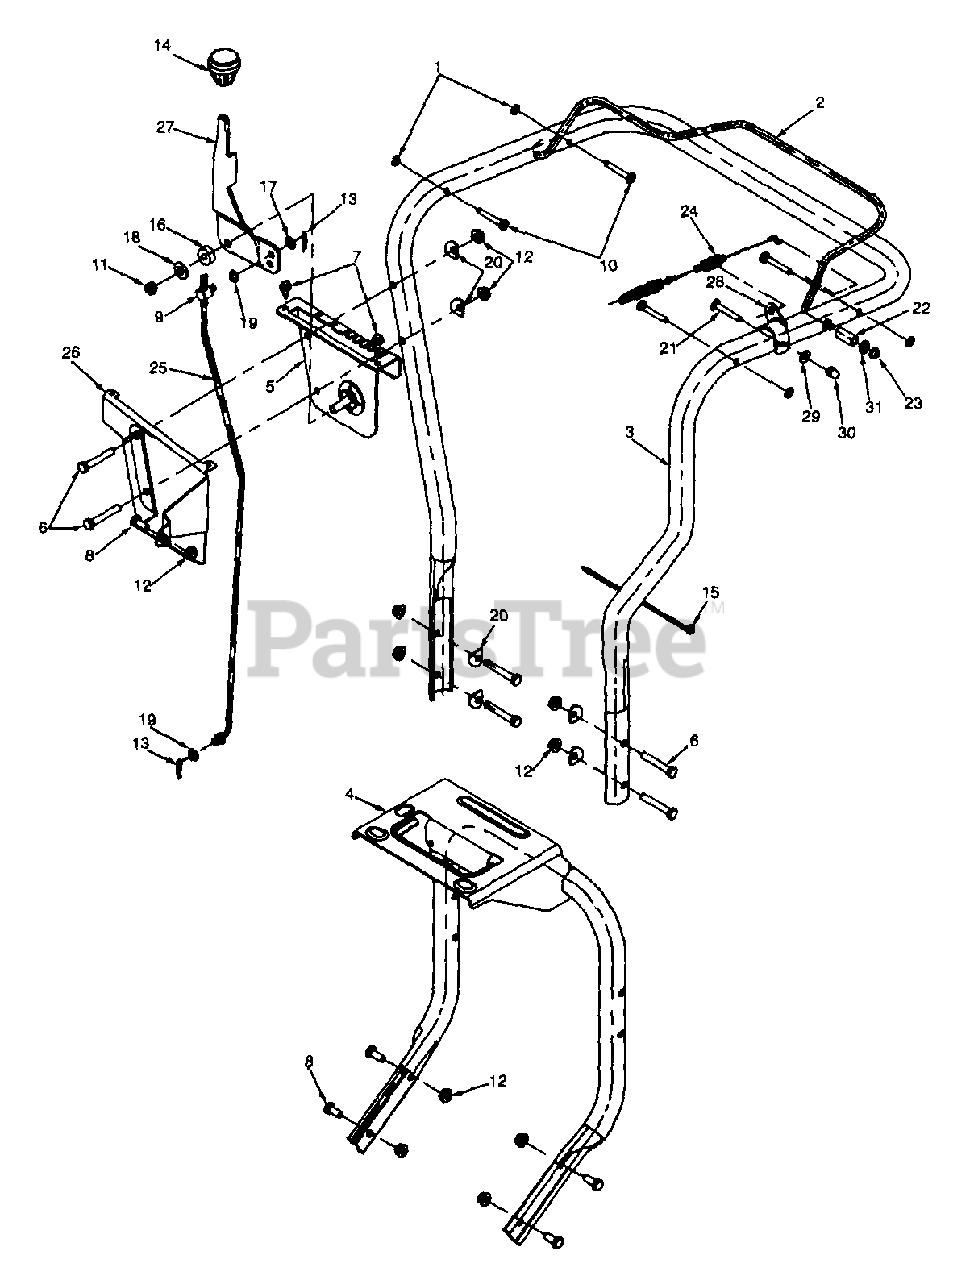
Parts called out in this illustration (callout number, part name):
1	Nut, Push, .25
2	Control Assembly, Clutch
3	Handle Assembly, Upper
4	Handle Assembly, Lower
5	Bracket Assembly, Shift
6	Screw, Hex Cap, 5/16-18 x 2.0
7	Screw, Hex Wash Hd, 4-14x
8	Screw, Hex Cap 5/16-18 x .75
9	Ferrule
10	Pin, Stud, .250 x 1.75
11	Nut, Hex Insert Jam Lock 3/8
12	Nut, Hex Flange Lock 5/16-18
13	Pin, Internal Cotter
14	Knob, Shift
15	Cable Tie
16	Rubber Washer
17	Washer, Flat .385 x .62 x .6
18	Washer, Flat, .406 x .875 x .059
19	Washer, Spring, .390 x .62
20	Washer, Saddle, .320 x .93
21	Carr. Bolt 1/4-20 x 1.75" Lg.
22	Spacer
23	Nut, Cap Speed
24	Cable, Clutch
25	Rod, Shift
26	Cover, Shift
30	Nut, Lock, Acorn 1/4-20
31	Washer, Flat 5/16
